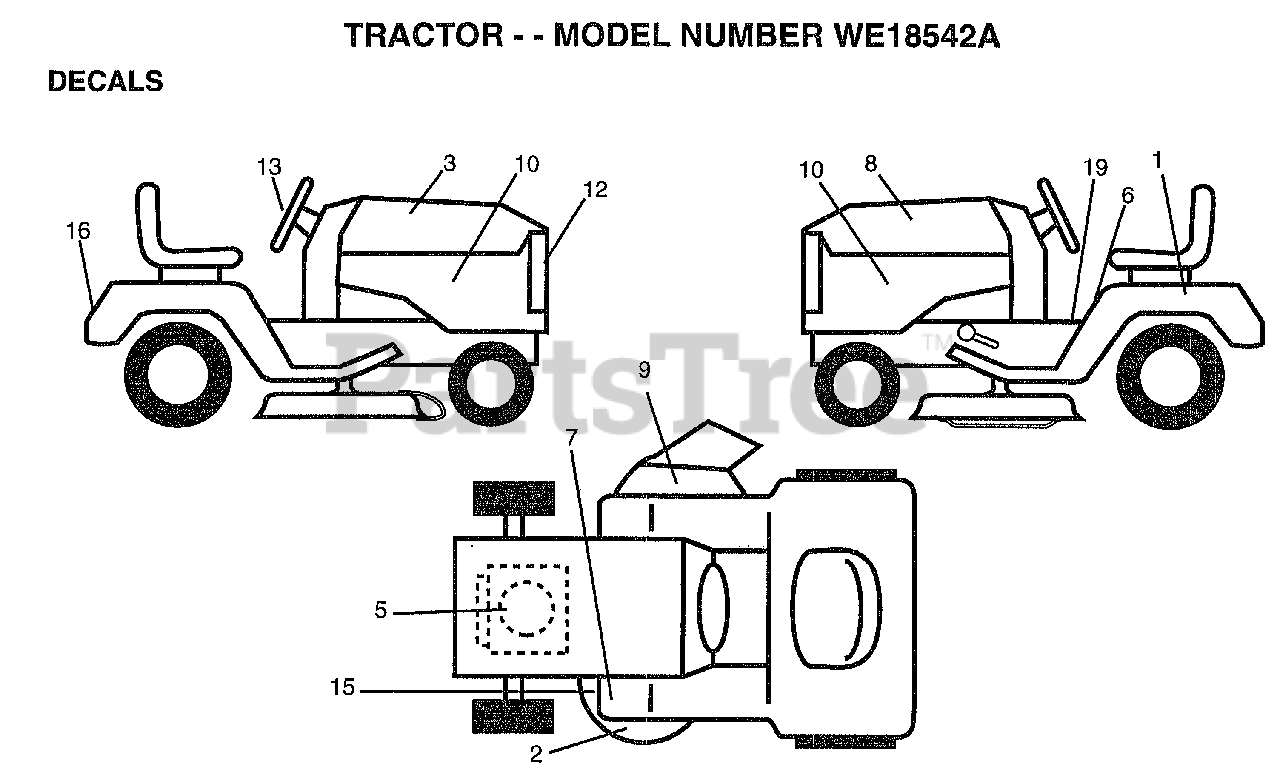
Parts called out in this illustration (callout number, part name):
1	DECAL.BATRY.3-3908
1	VALVE CAP
2	DECAL, DECK GRASSEATER
2	VALVE STEM LT
3	DECAL.HOOD.RH.
4	TUBE.5.3/4.5/6
5	DECAL, HP, ENGINE
5	"RIM ASM 6"" FRT"
6	DECAL.CAUT.ENG/FR
6	FITTING LT
7	DECAL T
7	"FLANGE, BEARING"
8	DECAL.HOOD.LH
8	"RIM AS 8"" REAR"
9	"DECAL, WARNING"
9	TIRE.20X8-8
10	DECAL.PNL.SIDE
10	TUBE.18X9.5-8
11	HUB CAP
12	DECAL, GRILLE LENS
13	DECAL, INS STRG WH
15	"DECAL-SCHEM,BELT"
16	DECAL.FENDER.LOGO
19	"DECAL.OPER,SDL"
